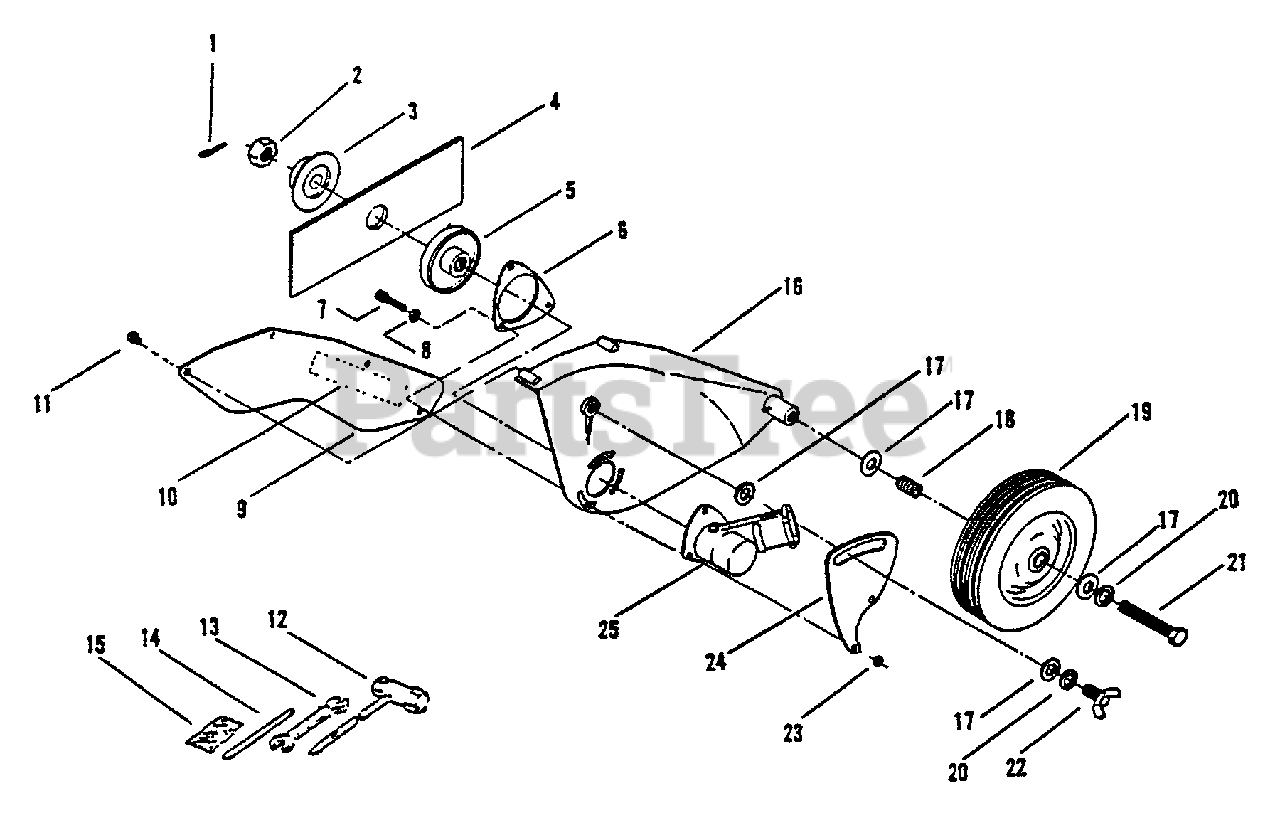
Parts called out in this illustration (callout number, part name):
1	PIN, COTTER 2×22
3	PLATE, ADAPTOR - LOWER
4	BLADE, EDGER
5	PLATE, ADAPTER - UPPER
6	PLATE, SHIELD Ø49.5 MM
7	BOLT 5×25
8	WASHER, CONE 5.2 MM
9	SHIELD ASSY, W/DECAL
10	LABEL - CAUTION
11	BOLT 4×10
12	T-WRENCH 17x-19 L200
13	SPANNER 8×10
14	TOOL, LOCKING 5×120 MM
15	PIN, COTTER 2×22 (PKG. OF 10)
16	WEAR PLATE
18	COLLAR 12
19	WHEEL - 6×1.5
20	WASHER, FLAT 5.5×10×0.8
21	BOLT - 8×60
22	THUMBSCREW - 8×20
23	LOCKNUT - 5
24	BRACKET, SHIELD
25	GEAR CASE ASSY
